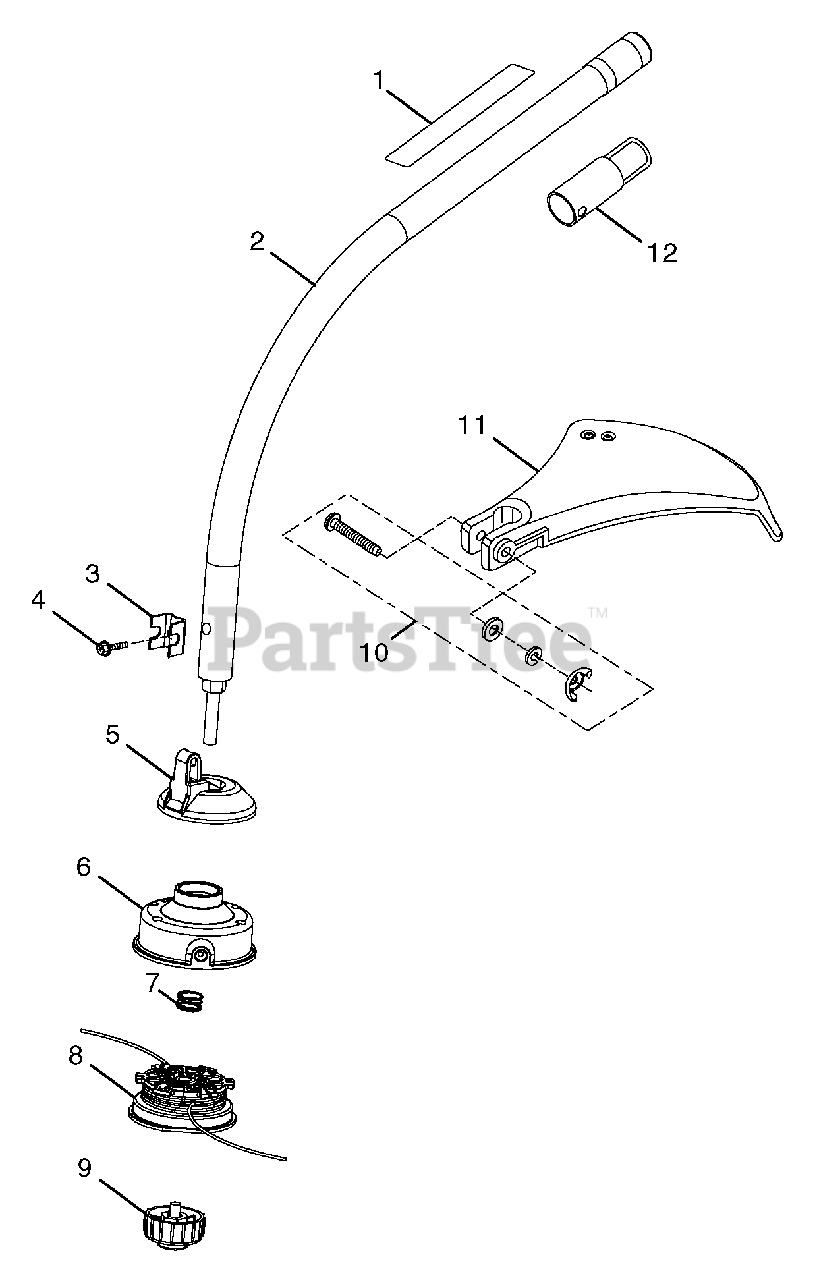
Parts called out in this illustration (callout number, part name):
1	Warning Label
2	Curved Shaft Assembly
3	Clamp
4	Screw
5	Grass Barrier
6	Trimmer Head
7	Compression Spring
8	Spool with Line (.095)
9	Retaining Cap,Right-hand Threads
10	Parts Kit
11	Grass Deflector Assembly
12	Storage Cap
